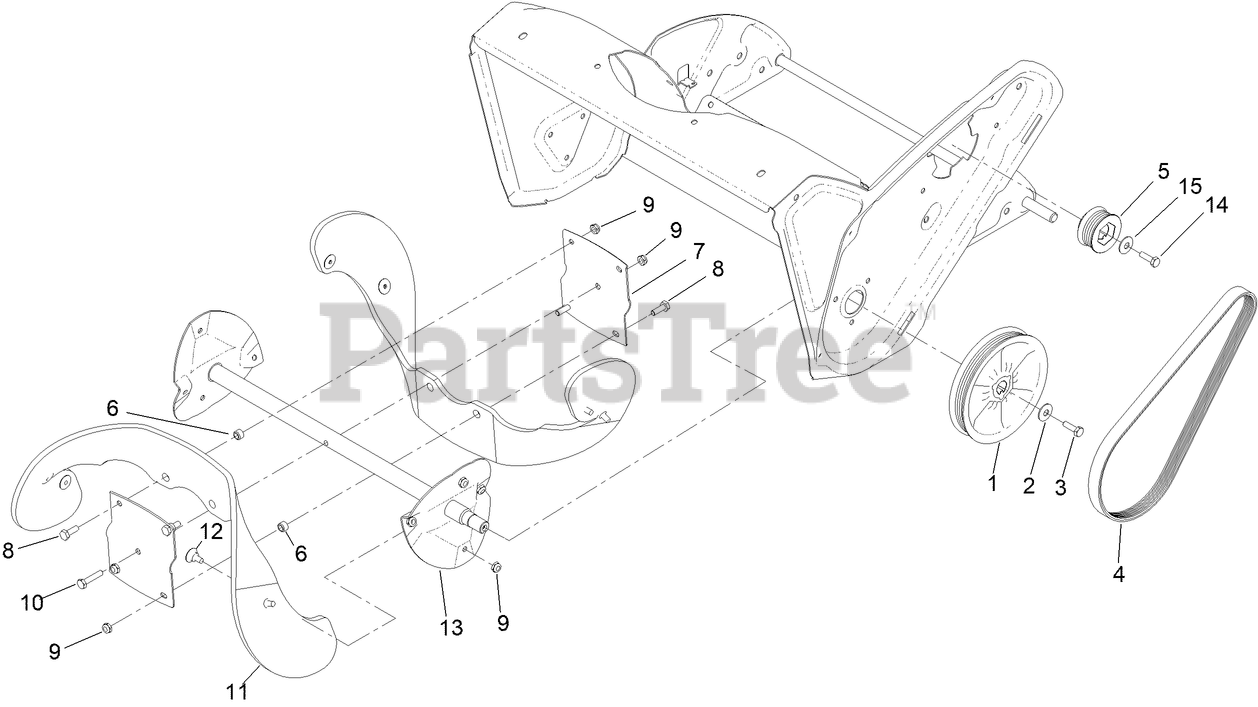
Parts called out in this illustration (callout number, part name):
1	PULLEY-ROTOR
2	WASHER-BELLEVILLE
3	SCREW-HH
4	BELT-V, RIBBED STRETCH
5	PULLEY-DRIVER (MACH)
6	SPACER-BLADE, ROTOR
7	HALF-ROTOR
8	SCREW-HH
9	NUT-LOCK, NI
10	SCREW-HH
11	BLADE-ROTOR
12	SCREW
14	SCREW-HH
15	WASHER-HARDENED
